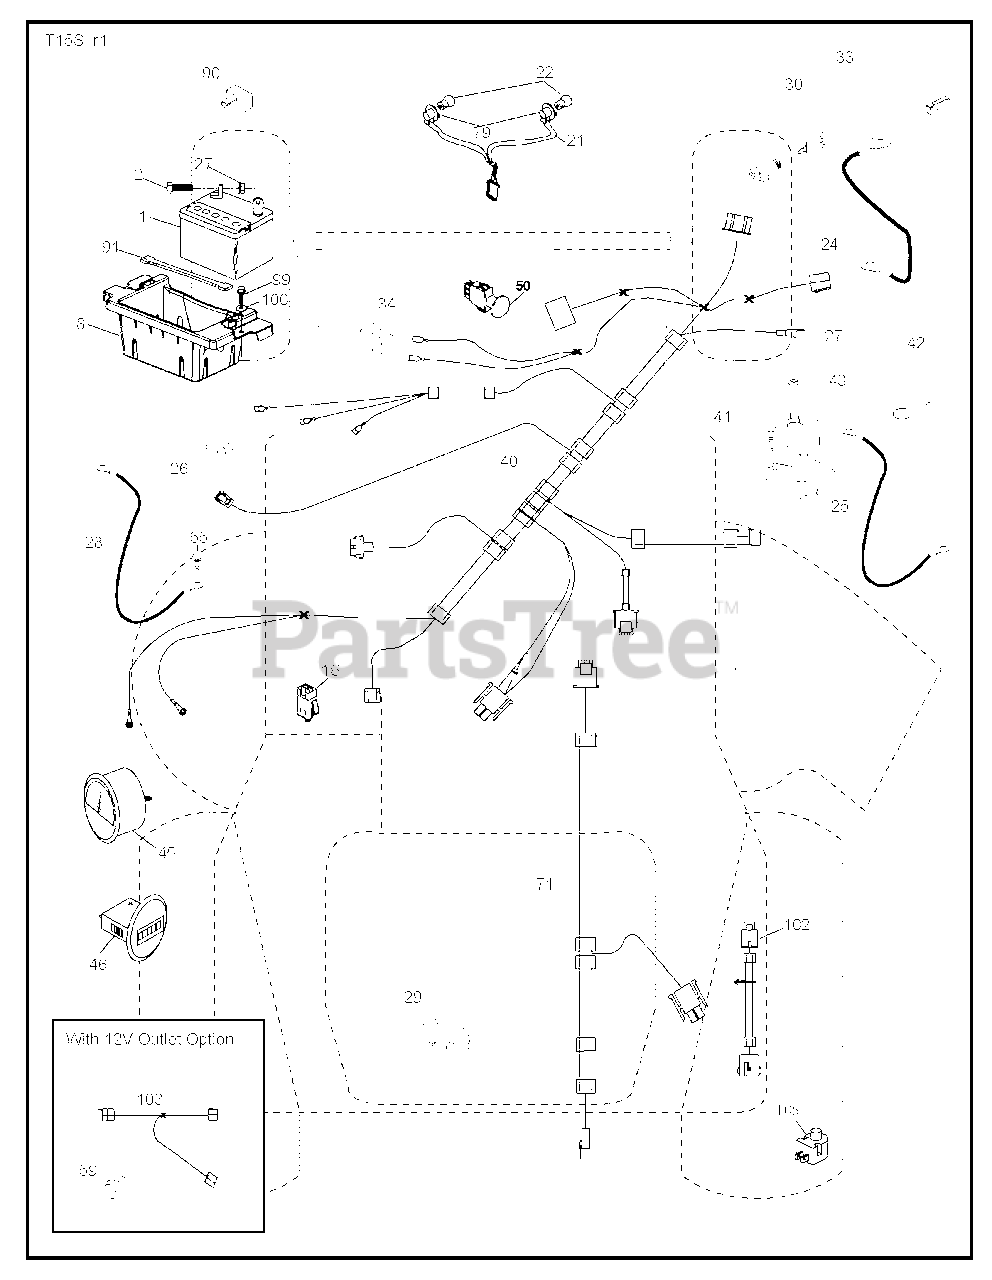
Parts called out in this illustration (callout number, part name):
1	REPL BY 532 12 38-99
8	BOX.BATTERY.MOUNT.FRONT.LT
16	SWITCH INTERLOOK PUSH-IN
21	HARNESS.LIGHT W/4152J BULBS
22	LIGHTBULB
24	CABLE.BATT.POS.WIRE.TG.DA SOL
25	CABLE.STARTER.6G.BL/RED.17.5
26	FUSE 20AMP
27	NUT
28	CABLE GROUND 6 GA 21" 90T BLK
29	SWITCH.SEAT.DELTA.OPC.
30	SWITCH.IGN.DELTA.W.LGH.ROS
33	KEY.CHAIN.BLISTER.PACK.GEN.INT
34	SWITCH LT
40	HARNESS IGN. DASH
41	SCREW
42	TERMINAL COVER
43	SOLENOID.W/BRASS.PLUNG
50	PTO SWITCH
55	SCREW 5/16"
71	HARNESS-CHASSIS SUB
79	BULB HOLDER ASM.
90	COVER.TERMINAL.BATTERY
91	STRAP, BATTERY MOUNT
99	SCREW HEXWSHR 1/4-20X3/4
102	HARNESS PIGTAIL PCH TEX ROS
105	REVERSE SWITCH
